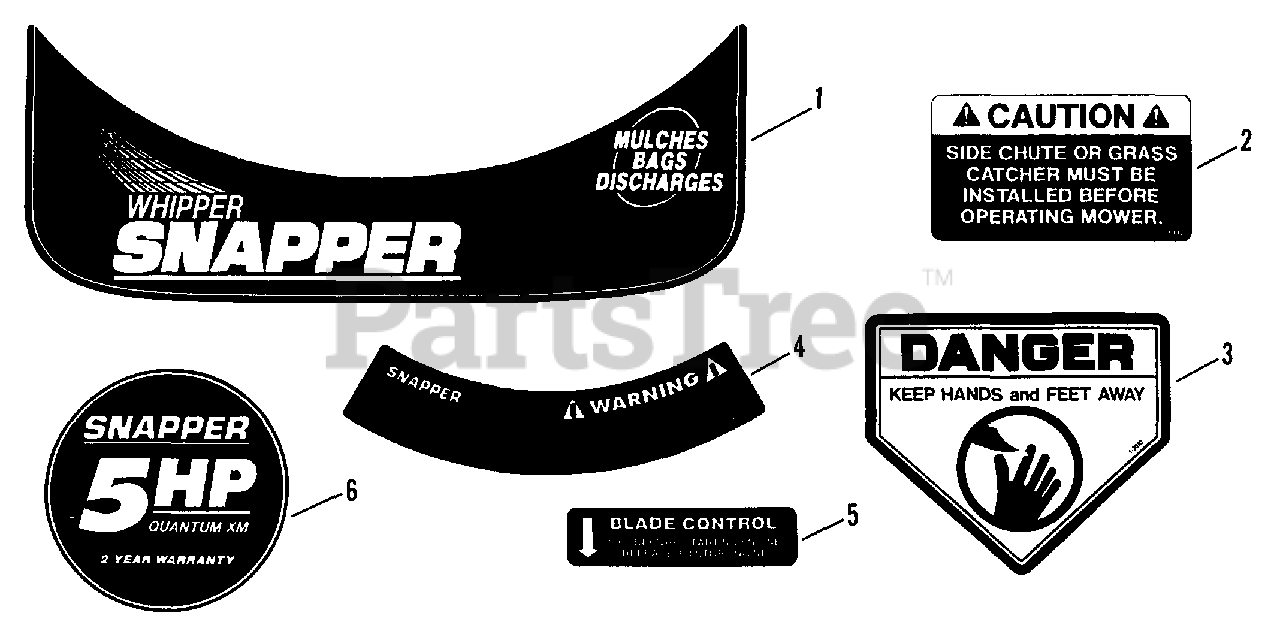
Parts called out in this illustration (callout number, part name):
1	DECAL, "WHIPPER" SNAPPER
2	DECAL, CAUTION (Discharge Opening)
3	DECAL, DANGER (Keep Hands & Feet Away)
4	DECAL, WARNING (Serial No. Blank)
5	DECAL, Blade Control
6	DECAL, SNAPPER 5HP Quantum XM
